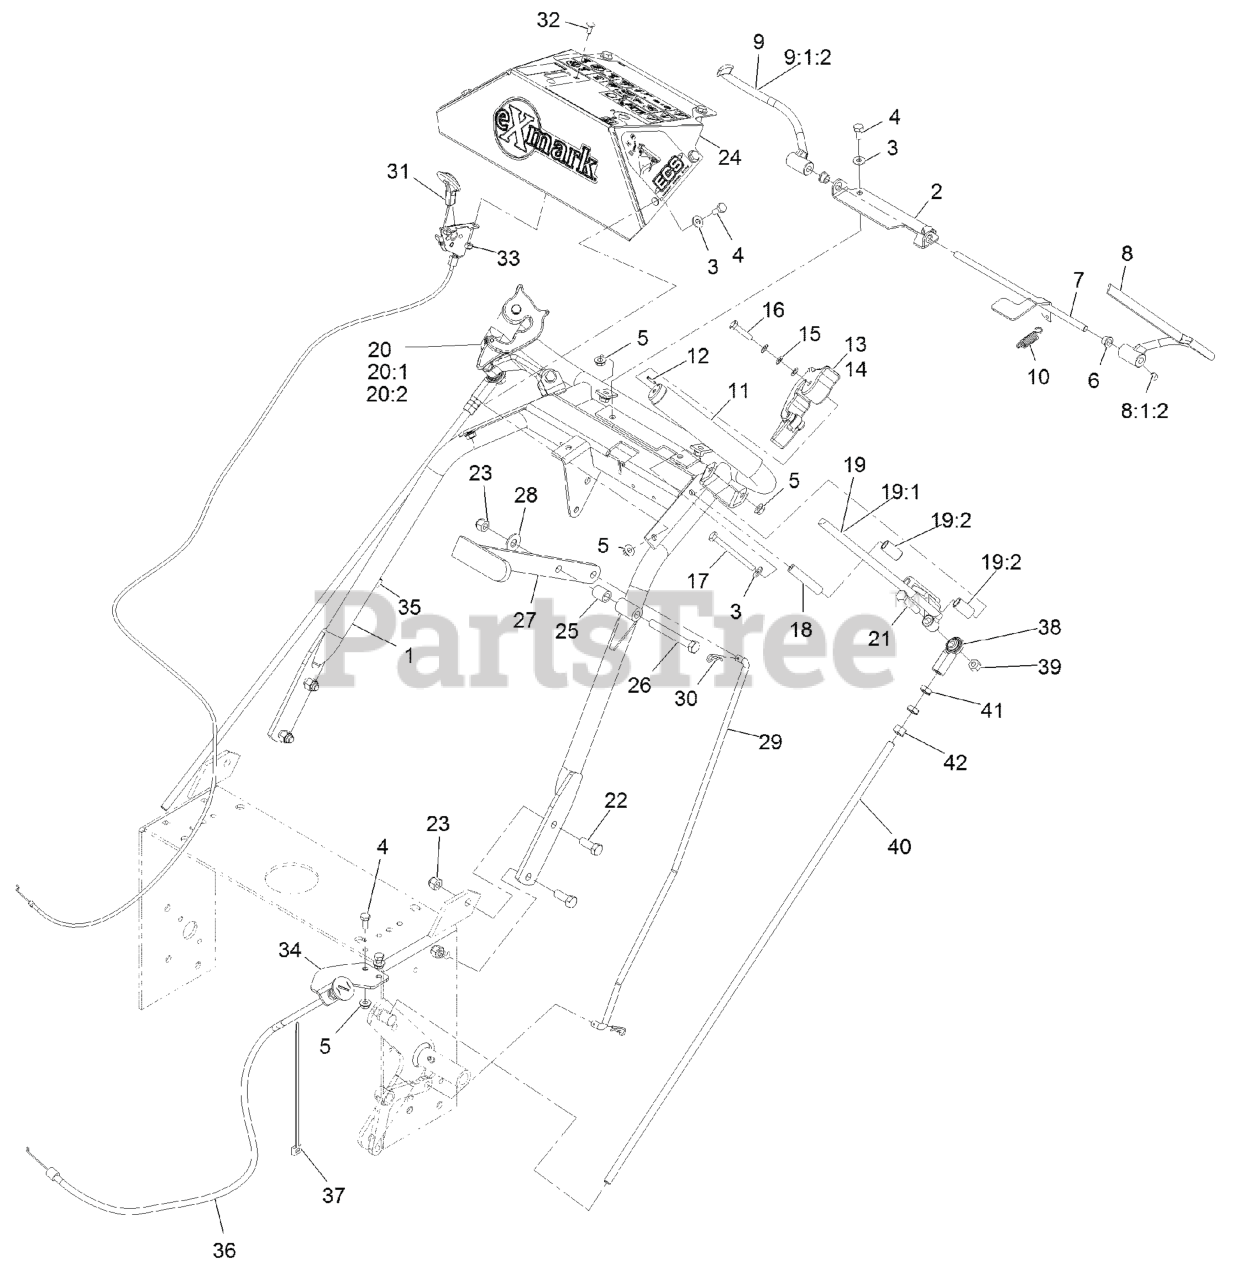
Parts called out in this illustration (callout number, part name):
1	WLD,UPPER ECS HANDLE
2	BRACKET,OPC AXLE
3	WASHER-FLAT
4	SCREW-HH
6	BUSHING-NYLON
7	WLD,OPC LEVER AXLE
8	WLD,LH OPC LEVER
8:1:2	SCREW-SET
9	WLD,RH OPC LEVER
9:1:2	SCREW-SET
10	SPRING-EXTENSION
11	GRIP-BAR, HANDLE
12	PIN-SPRING
13	ASM,LH THUMB LATCH
14	ASM,RH THUMB LATCH
15	WASHER-SPRING
16	SCREW-HH
17	SCREW-HH
18	BUSHING-LEVER, DRIVE
19	DRIVE LEVER-ASM, LH
19:1	WLD,LH DRIVE LEVER
19:2	BUSHING, SLEEVE
20	DRIVE LEVER-ASM, RH
20:1	WLD,RH DRIVE LEVER
20:2	BUSHING, SLEEVE
21	SCREW-HH
22	SCREW-HH
23	NUT-LOCK, NI
24	ASM, CONSOLE W/DECALS
25	BUSHING-LEVER, LIFT
26	SCREW-HH
27	CLUTCH LEVER-W/GRIP
28	WASHER-FLAT
29	LINKAGE,UPPER BLADE (PLT)
30	PIN-COTTER
31	CONTROL, THROTTLE
31	Control, Throttle
32	BOLT-CARR
33	NUT-LOCK, NI
34	BRACKET-CABLE, CHOKE
35	CLIP-CABLE
36	CABLE-CHOKE
36	Cable-Choke
37	TIE-PLASTIC
38	JOINT-BALL, END
39	NUT-LOCK, NI
40	LINKAGE,DRIVE (PLT)
41	NUT-HJ
42	NUT-HEX
